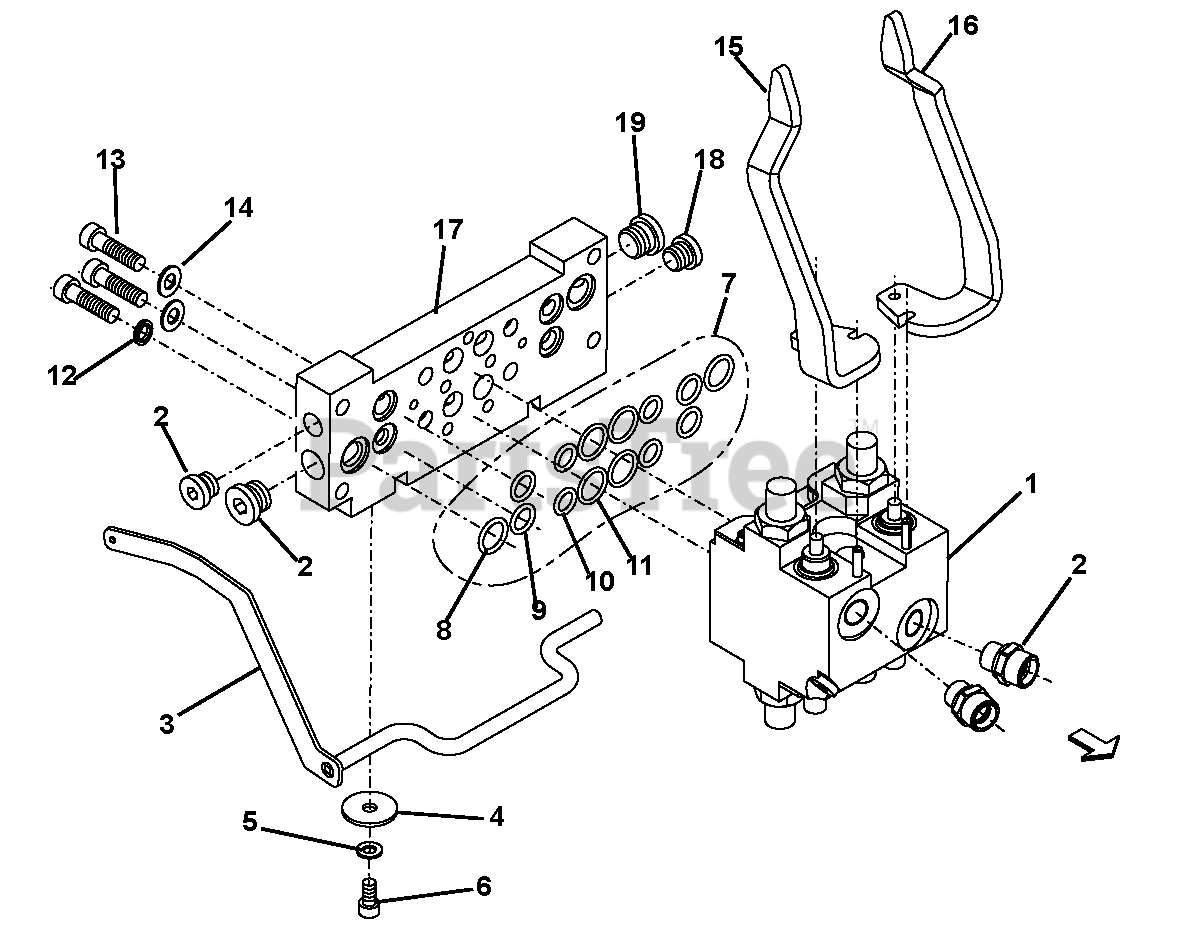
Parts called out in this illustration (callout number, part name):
1	Assembly, Valve
2	Connection
4	Washer, BN 732 9 x 35 x 2.5
5	Clutch Bellhousing
6	Screw, D912 M8 x 16
7	Kit, Gasket
8	O-Ring, 19 x 3.00
9	O-Ring, 15 x 3.00
10	O-Ring, 13 x 3.00
11	O-Ring, D3770 20.24 x 2.62
12	Seals, Bonded 10.35 x 16 x 2
13	Screw, D912 M10 x 45
14	Washer, Form Steel 10.2/20.25 x 1.6
15	Lever, Control
16	Lever, Control
17	Connection Plate
18	Screw, Lock M16 x 1,5
19	Screw, Lock, M20 x 1,5
